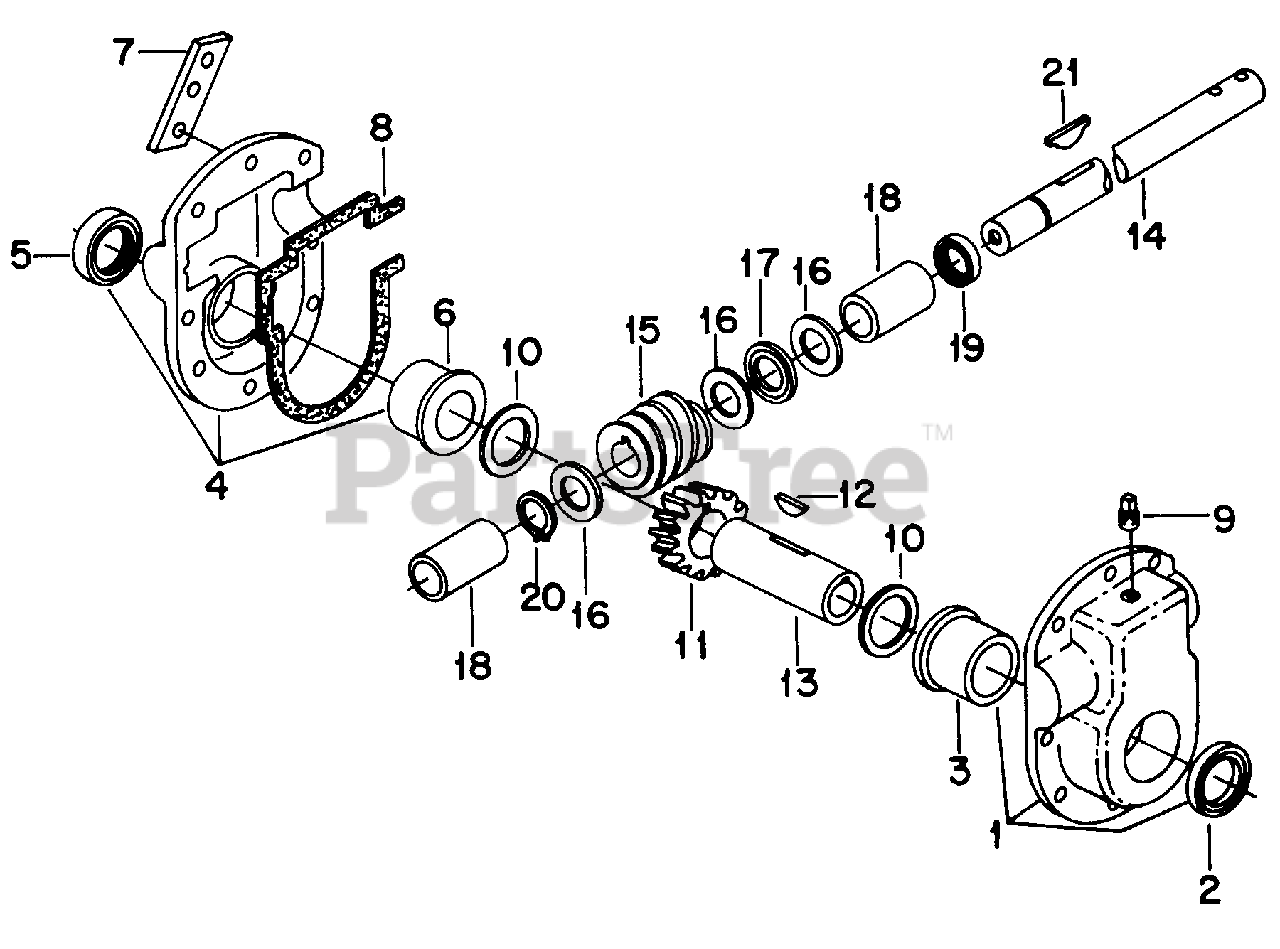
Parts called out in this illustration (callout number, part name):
1	Housing Assy, Gear Box LH
2	Seal, Oil
3	Bearing, Flange
4	Housing Assy, Gear Box RH
5	Seal, Oil
6	Bearing, Flange
7	Support, Gear Housing
8	Gasket, Gear Box Housing
9	Plug, Vent
10	Washer, 1.50 X 2.0 X .30 Flat
11	Gear, Worm
12	Key, 1/4 X 3/4 SAE 91 Woodruff
13	Tube, Worm Gear Shaft
14	Shaft, Blower Drive
15	Gear, Blower Worm
16	Washer, .88 X 1.4 X .155 Flat
17	Bearing, Thrust
18	Sleeve
19	Seal, Oil
20	Ring, .810 Ext Ret
21	Key, 3/16 X 3/4 Dia Hi-Pro #9
